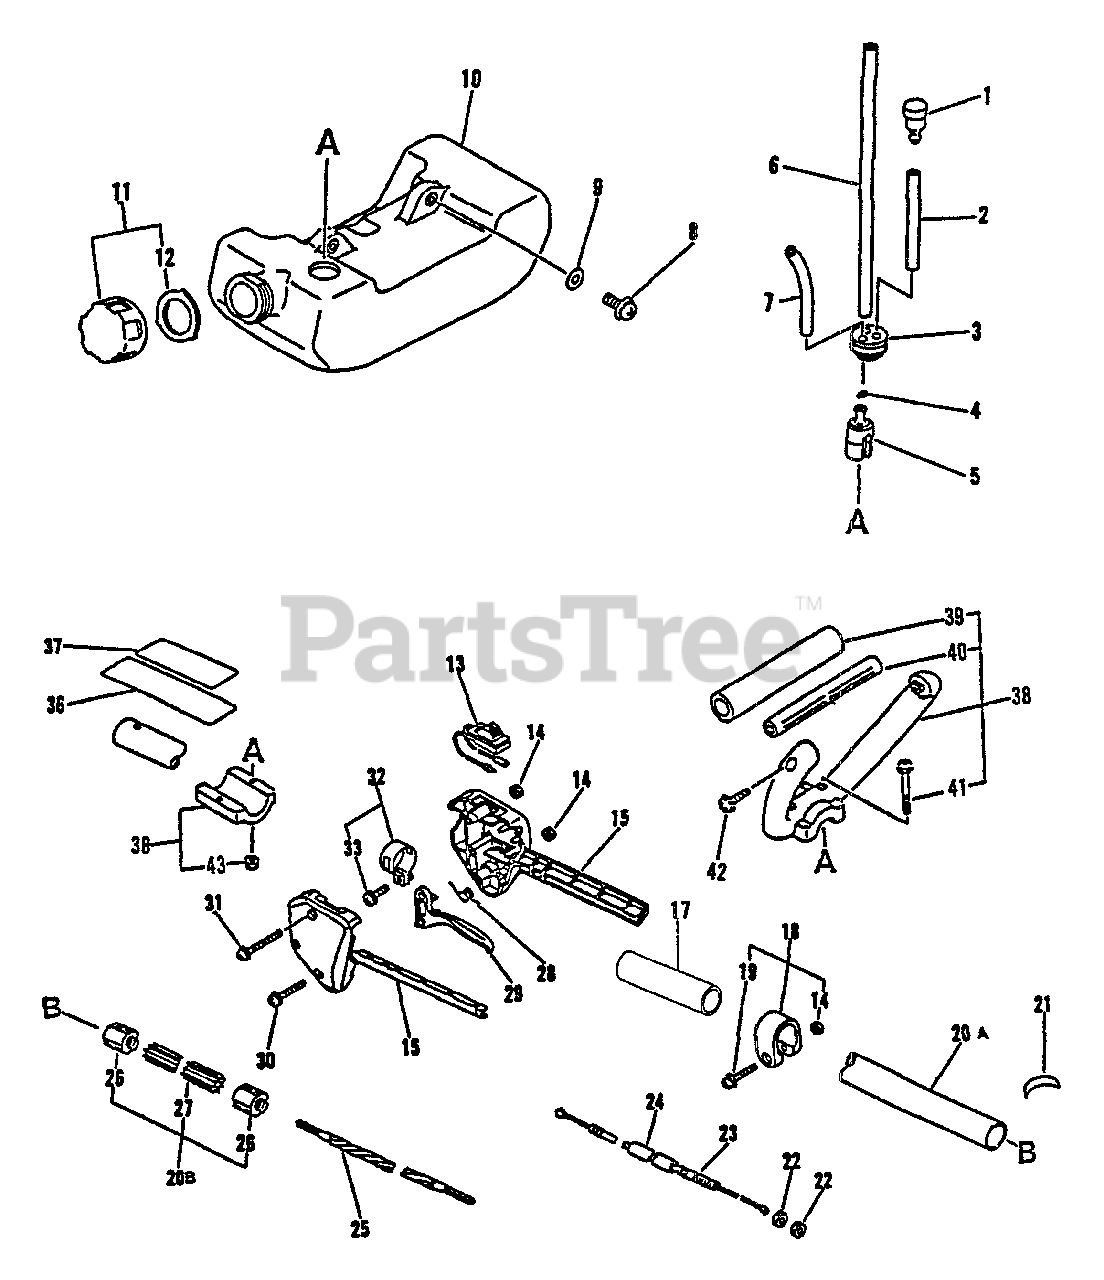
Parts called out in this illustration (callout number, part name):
1	VENT, FUEL TANK
2	PIPE - 3X5X70 -- BLACK
3	GROMMET
4	CLIP - 6
5	FILTER, FUEL
6	PIPE - 3X5X180 -- BLACK
7	PIPE - 3X6X90 -- CLEAR
8	SCREW - 5X16
9	WASHER - 5
10	TANK, FUEL
11	CAP ASSY
12	GASKET, CAP
13	IGNITION SWITCH ASSY
15	CONTROL HANDLE KIT
17	GRIP, HANDLE
18	CLAMP KIT
19	SCREW - 5X28
20	MAIN PIPE ASSY
21	LABEL - ALIGNMENT
23	CABLE, THROTTLE
24	TUBE - VINYL
25	DRIVESHAFT - FLEXIBLE
27	LINER - FLEXIBLE
28	SPRING, TRIGGER
29	TRIGGER, THROTTLE
30	SCREW - 5X25
31	SCREW - 5X35
32	CLAMP KIT
33	SCREW - 5X14
34	SCREW - 5X40
35	WASHER - 5
36	LABEL - CAUTION
37	LABEL - CAUTION
38	LOOP HANDLE ASSY
39	GRIP, HANDLE
41	SCREW - 6X35
42	SCREW - 5X30
43	LOCKNUT - 6
